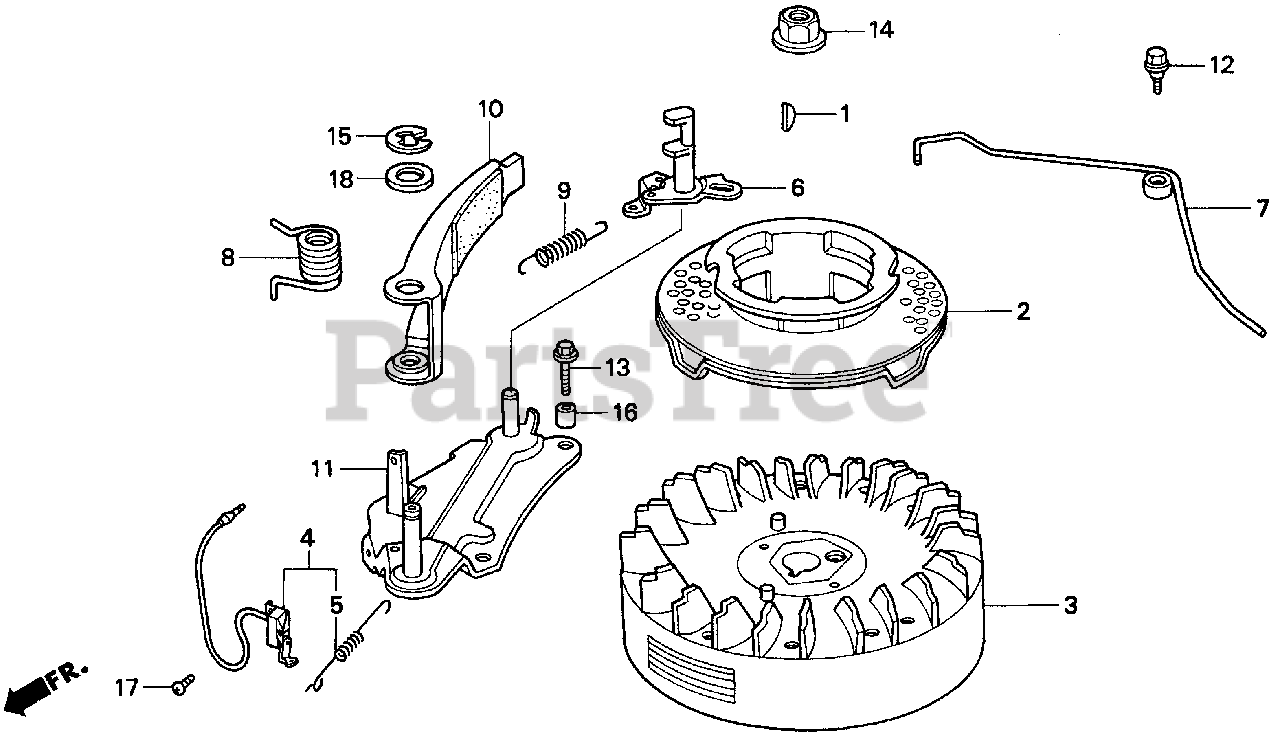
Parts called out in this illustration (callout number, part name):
1	KEY, SPECIAL WOODRUFF (25X18)
2	PULLEY, STARTER
3	FLYWHEEL (BAND BRAKE)
4	SWITCH ASSY., ENGINE STOP
5	SPRING, SWITCH CONTROL
6	CAM, BRAKE
7	ROD, THROTTLE RETURN
8	SPRING, BRAKE
9	SPRING, BRAKE RETURN
10	BRAKE
11	BASE, BRAKE
12	BOLT, FLANGE (6MM)
13	BOLT, FLANGE (6X23)
14	NUT, SPECIAL (14MM)
15	E-RING (10MM) (NOT AVAILABLE)
16	PIN, DOWEL (8X9)
17	SCREW, PAN (4X8)
18	WASHER, FLAT (12MM)
